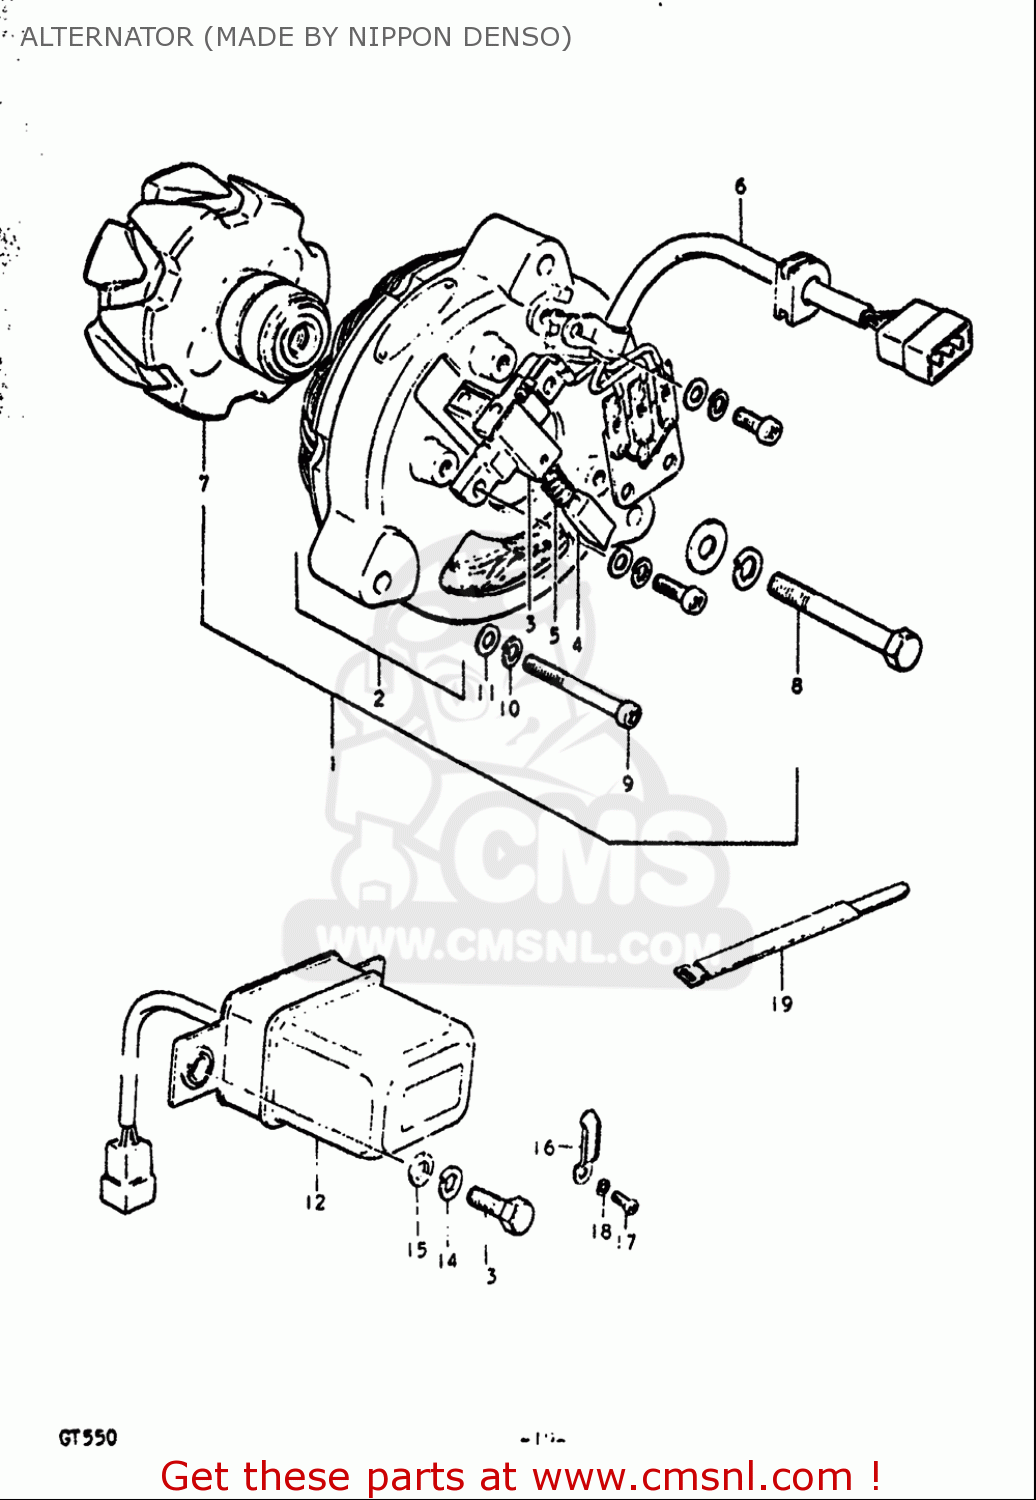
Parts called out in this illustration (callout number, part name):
3	HOLDER,CARBON BRUSH
4	BRUSH
5	SPRING
8	BOLT
9	SCREW
10	WASHER,LOCK
11	WASHER
12	REGULATOR ASSY,VOLTAGE
13	BOLT
14	WASHER,LOCK
15	WASHER
16	CLAMP
17	SCREW
18	WASHER,LOCK
19	CLAMP
